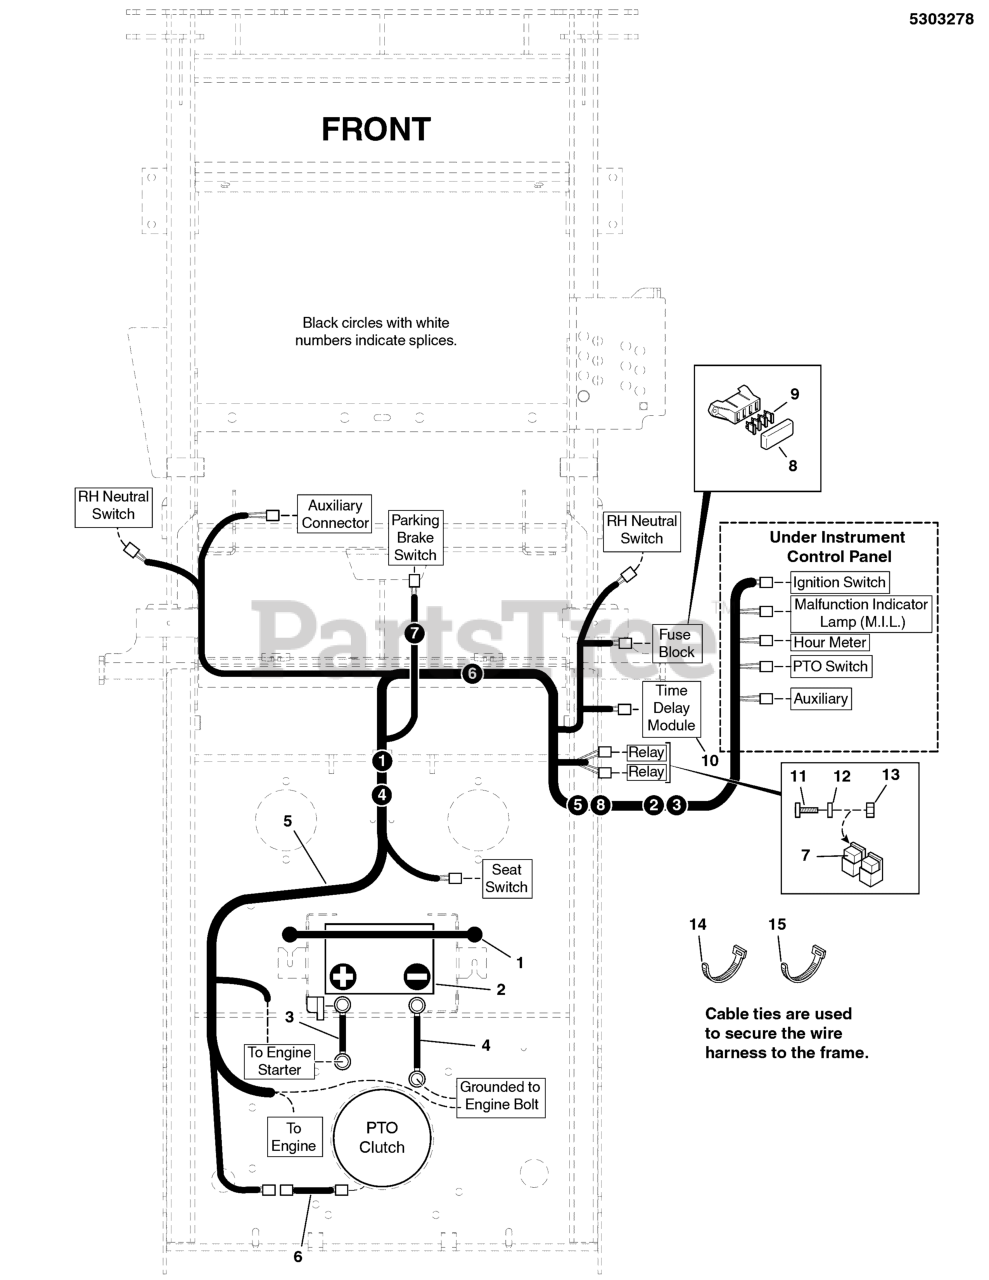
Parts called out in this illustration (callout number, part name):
1	STRAP-BLACK RUBB
2	BATTERY, WET ( BCIU1, 350 CCA)
3	BATTERY CABLE, POSITIVE, 22
4	BATTERY CABLE, NEGATIVE, 10
5	WIRE HARNESS, MAIN, KOHLER EFI, 2000
6	CLUTCH JUMPER W/DIODE, WARNER
7	RELAY, 12V, 40A
8	COVER, VINYL FUSEBLOCK
9	FUSE, ATO, 20 AMP
10	MODULE, TIME DELAY
11	BOLT, 1/4-20 X 3/4 GD5 YZ
12	WASHER, 1/4 SAE
13	NUT, 1/4-20 HEX SERR. FLANGE
14	TIE, SELF-LOCKING, 12"
15	TIE,SELF-LOCKING, 6"
